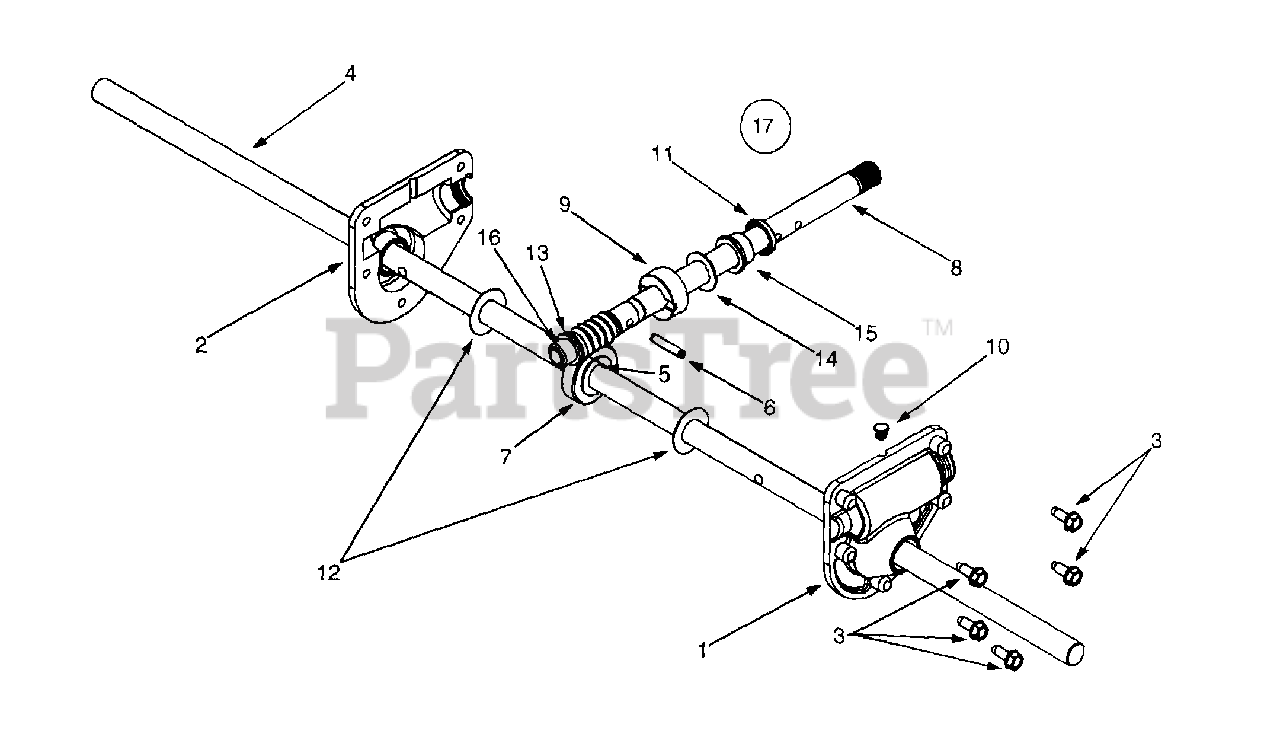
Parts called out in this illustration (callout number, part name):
1	RH Reducer Housing
2	LH Reducer Housing
3	Hex Screw 1/4-20 x .75
4	Spiral Axle 24"
5	Key
6	Pin-Spiral
7	Worm Gear, 20T
8	Worm Shaft
9	Thrust Collar
10	Grease Plug
11	Grease Seal
12	Flat Washer .76 x 1.5 x .030
13	Flat Washer .508 x 1.0 x .020
14	Flat Washer .76 x 1.5 x .060
15	Flange Bearing .75 x 1.0 x .59
16	Flange Bearing .75 x 1.0 x .925
17	Ass'y. Complete 24"
